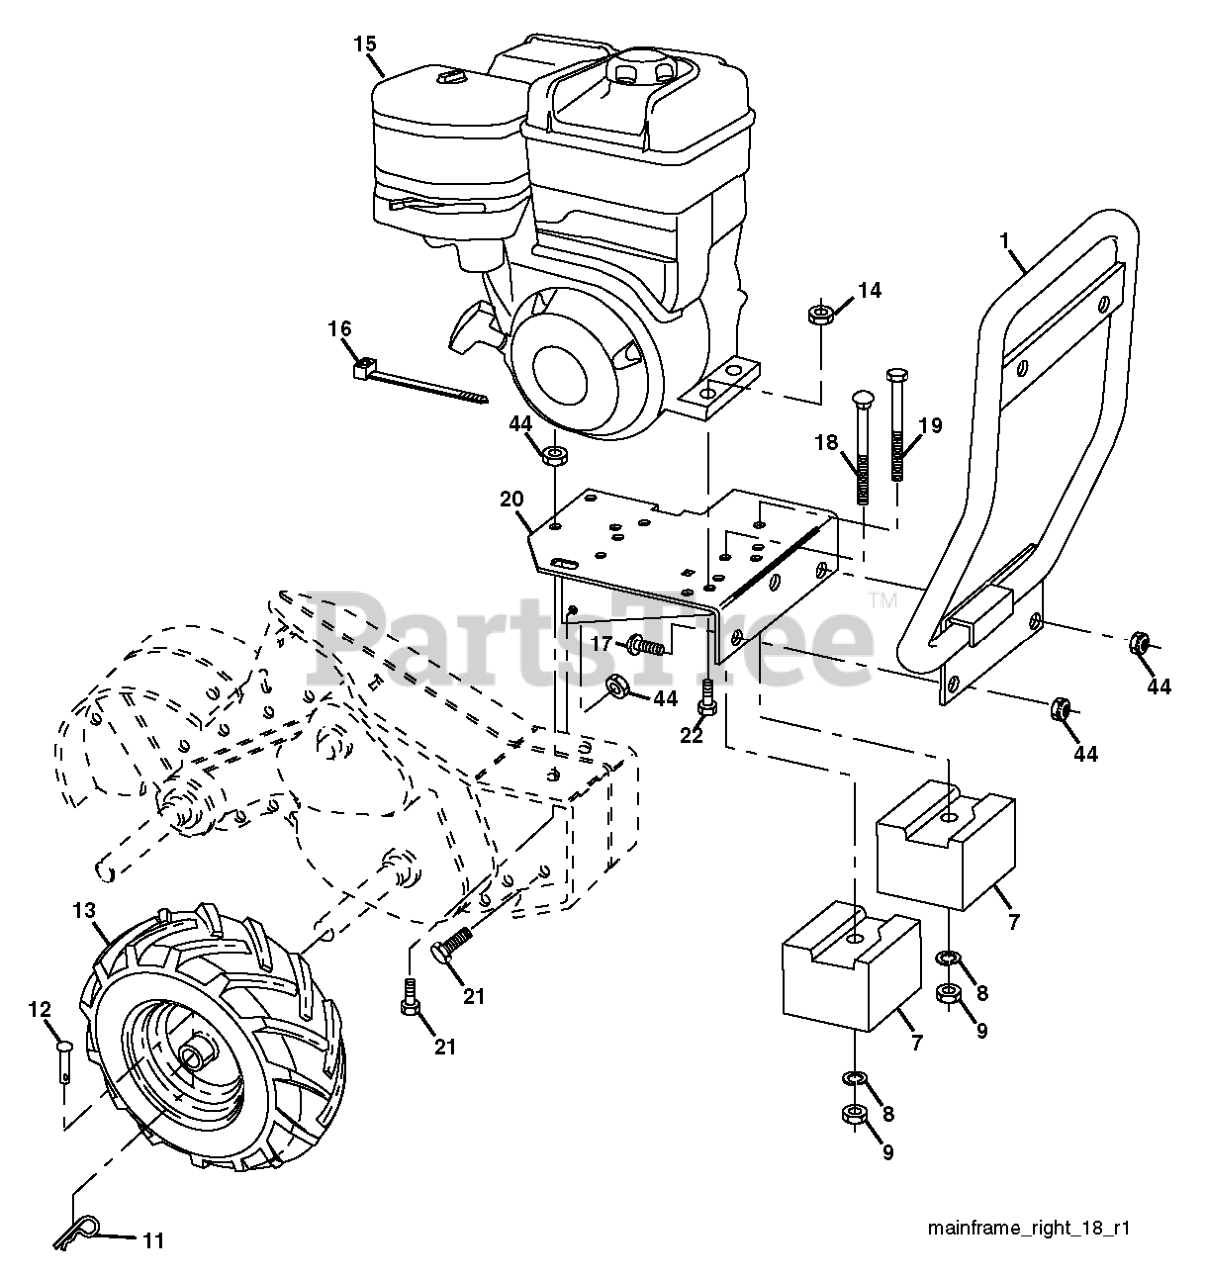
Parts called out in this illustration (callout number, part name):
1	BUMPER.ASM.9HP.TILLER
7	COUNTERWEIGHT
8	WASHER, LOCK 3/8
9	NUT.HEX.3/8-16UNC
11	SPRING TI
13	TIRE.16X4-8.CHEVRON.TILLER
13	RIM 2.75 X 8.0 X 1"ID.TILLER
13	VALVE STEM LT
14	LOCKNUT-FLANGE 5/16-18
16	TIE GUIDE
17	BOLT D
18	Bolt, Carriage 3/8-16 x 4-1/2
19	BOLT, HEX 3/8-16X4-1/2
20	Base Engine
21	BOLT
22	BOLT
